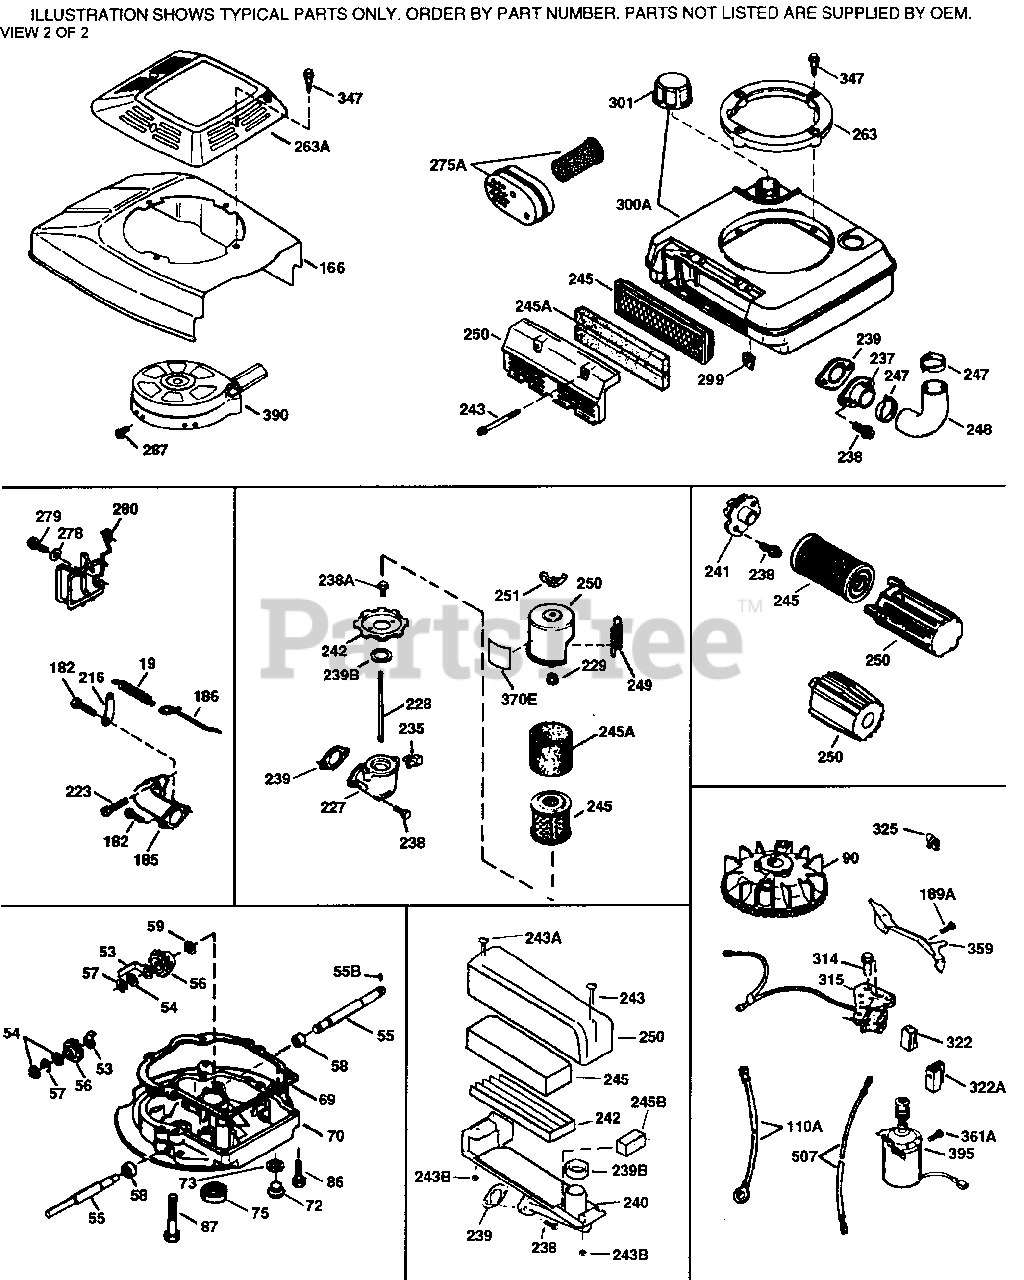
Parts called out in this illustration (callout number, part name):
19	Extension Spring
69	Mounting Flange Gasket
70	Mounting Flange (Incl. 72 thru 83)
72	Oil Drain Plug (Incl. 73)
73	Drain Plug Gasket
75	Oil Seal
86	Screw, 1/4-20 x 1-1/4"
90	Flywheel
110A	Ground Wire
182	Screw, 1/4-28 x 7/8"
185	Intake Pipe
186	Governor Link
223	Screw, 1/4-20 x 1"
238	Screw, 10-32 x 49/64"
239	* Air Cleaner Gasket
241	Air Filter Collar
245	Air Filter (Paper) (also available in Packaged Part #740095 (Qty.2))
250	Air Filter Cover (Craftsman)
275A	Spark Arrestor Muffler (Optional) (In cl. 284,284A,416,417)
287	Screw, 8-32 x 21/64"
301	Fuel Cap
390	Rewind Starter NOTE: This engine cou ld have been built with 590688 starte r. Refer to the design of the air int ake louvers for part identification. Individual starter parts do not inter change.
999	Summer Maintenance Kit (incl. Oil, Sp ark Plug, Air Cleaners (2), & Ultra-F resh)
